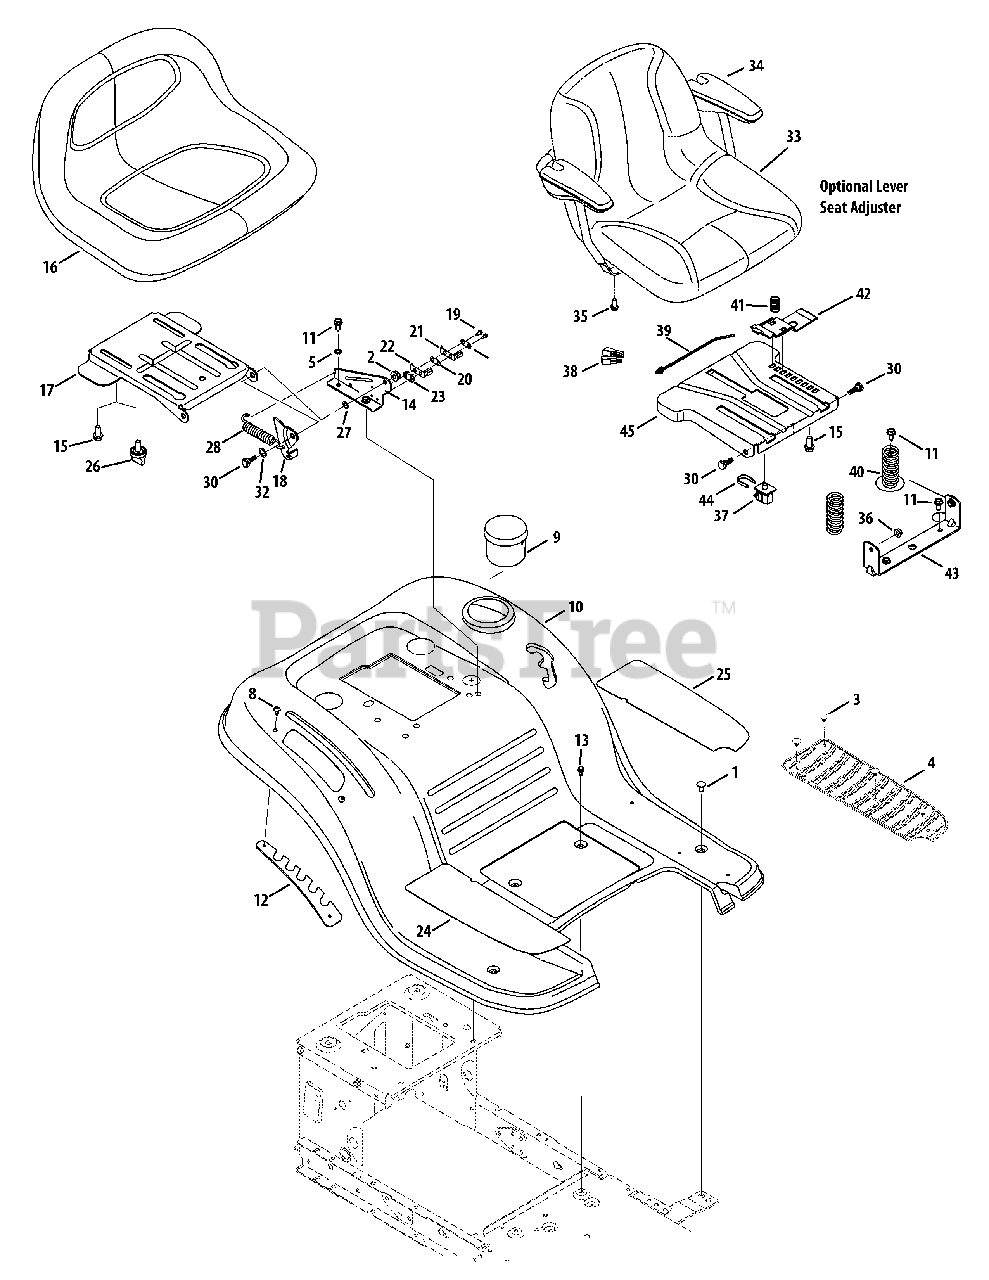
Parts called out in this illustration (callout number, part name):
1	Carriage Bolt 1/4-20 x .62
2	Flange Locknut 5/16-18 Gr. F, Nylon
3	Ratchet Clip
4	Foot Pad, RH
4	Foot Pad, LH
5	Lockwasher 5/16 ID
6	Flat Washer .510 x .750 x .033
8	Tap Screw 1/4-20 x .50
9	Cup Holder
10	Fender
11	S-Tapp Scr 5/16-18 x .75
12	Lift Adjustment Bracket
13	Hex Wash S-Tapp Scr 1/4-20 x .50
14	Seat Mounting Bracket
15	Screw 3/8-16 x .875
16	Seat, Low Back
17	Seat Pivot Bracket
18	Seat Lift Bracket
19	Hex Wash HD AB S-Tapp Scr #8-.50
20	Insulator Plate
21	Spring Switch
22	Seat Spring Switch
23	Insulator Plate
24	Foot Pad, Abrasive, RH
25	Foot Pad, Abrasive, LH
27	Cupp. Washer .345 ID x .88 OD x .060
28	Extension Spring .84 Dia. x 4.6
30	Shoulder Screw
32	Flat Washer .510 x .75 x .033
33	Seat, High Back, Blk Cloth (w/arm rest option)
34	Arm Rest Kit
35	Pan TT Screw 5/16-18 x .75
36	Flange Locknut 5/16-18 Gr. 5
37	Seat Switch
38	Seat Switch Jumper Harness
39	Cable Tie
40	Compression Spring 1.28 x 3.125
41	Compression Spring .68 x 1.065 x .055
42	Seat Adjustment Lever
43	Seat Pivot Bracket
44	Retaining Clip
45	Seat Mounting Bracket
